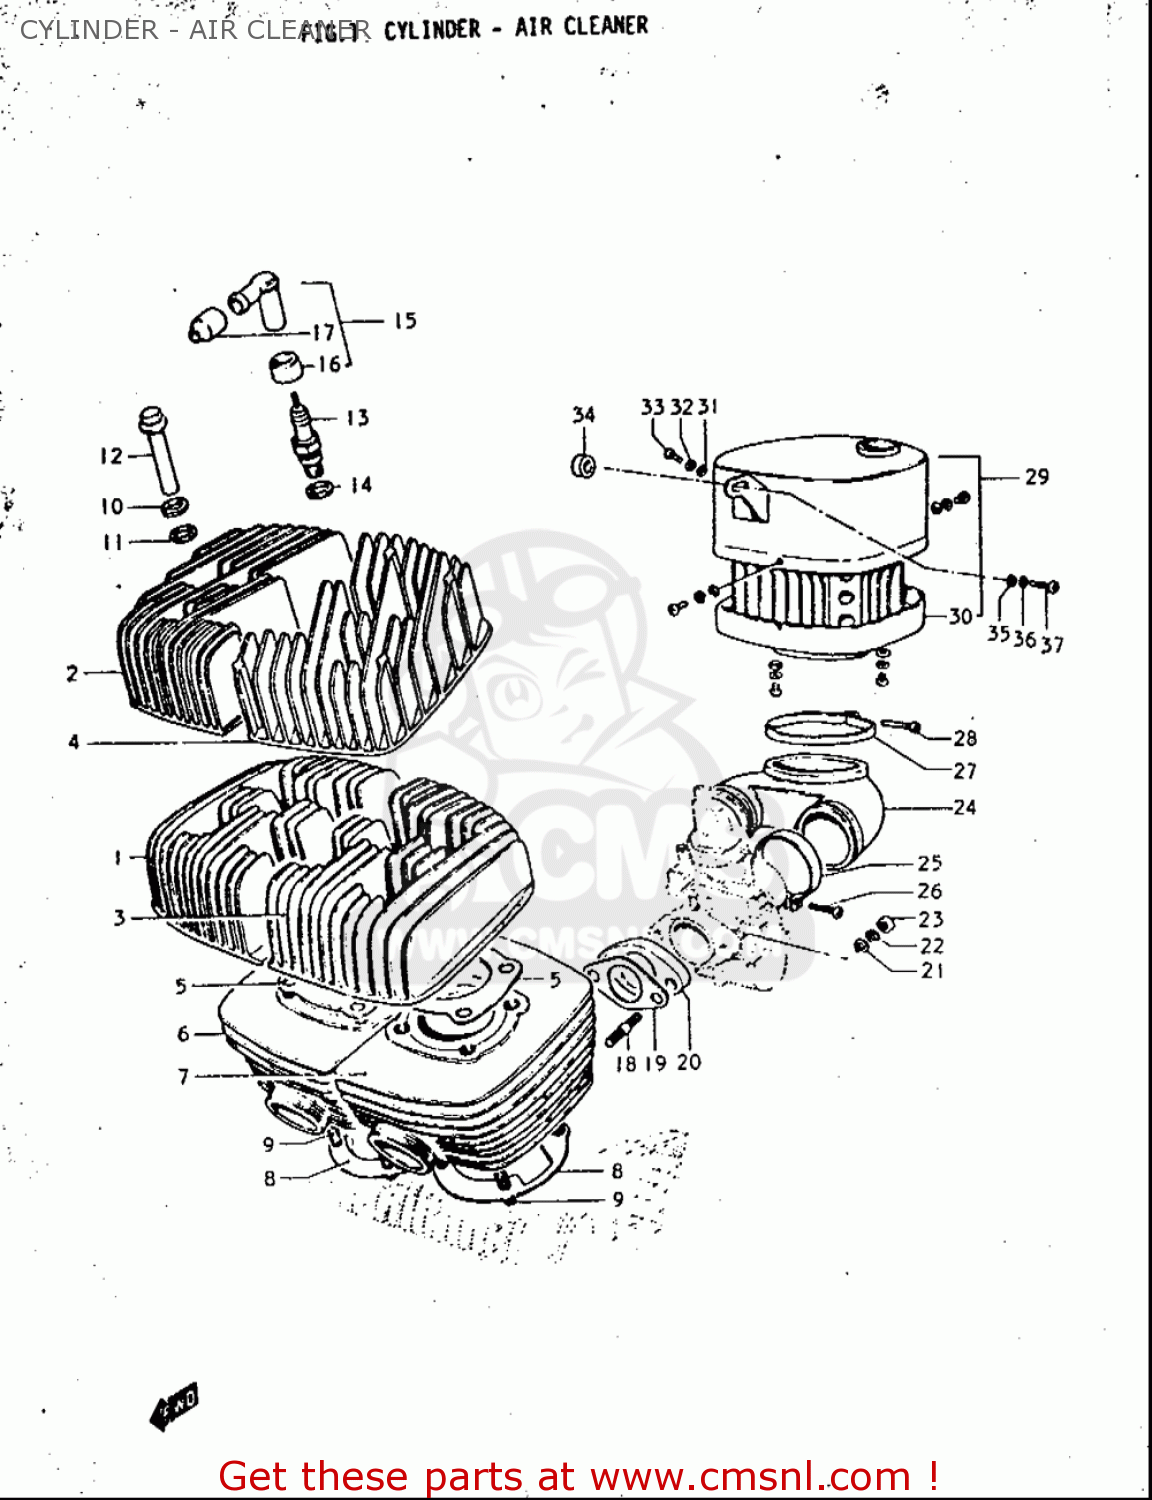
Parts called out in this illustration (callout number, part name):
5	GASKET,CYLINDER HEAD (NAS)
8	GASKET,CYLINDER (NAS)
9	BOLT,STUD
10	WASHER,LOCK
11	WASHER
12	NUT (8MM)
13	PLUG,SPARK(B7HS)
14	GASKET(14X19.2X2) (NAS)
17	SEAL,HIGH TENSION CORD
18	STUD BOLT
19	GASKET,CARBURETOR (MCA)
21	WASHER
22	WASHER,LOCK
23	NUT
25	CLAMP
26	SCREW
27	CLAMP
28	SCREW
30	FILTER ASSY
31	WASHER
32	WASHER,LOCK
34	WASHER
36	WASHER,LOCK
